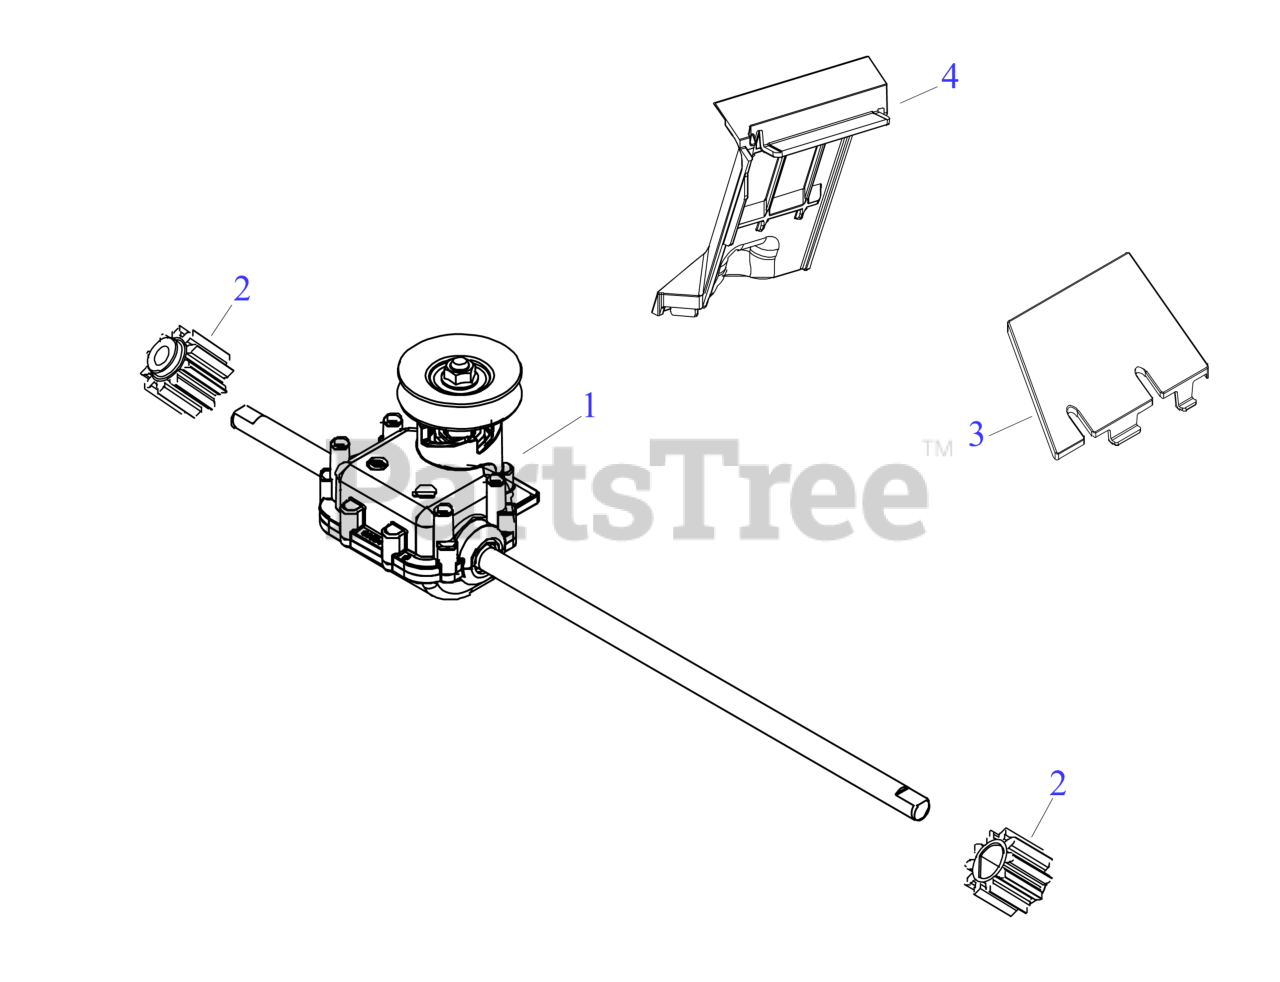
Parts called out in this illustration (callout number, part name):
1	TRANSMISSION
2	SPUR GEAR (10T)
3	TRANSMISSION COVER (REAR)
4	TRANSMISSION COVER (REAR)
